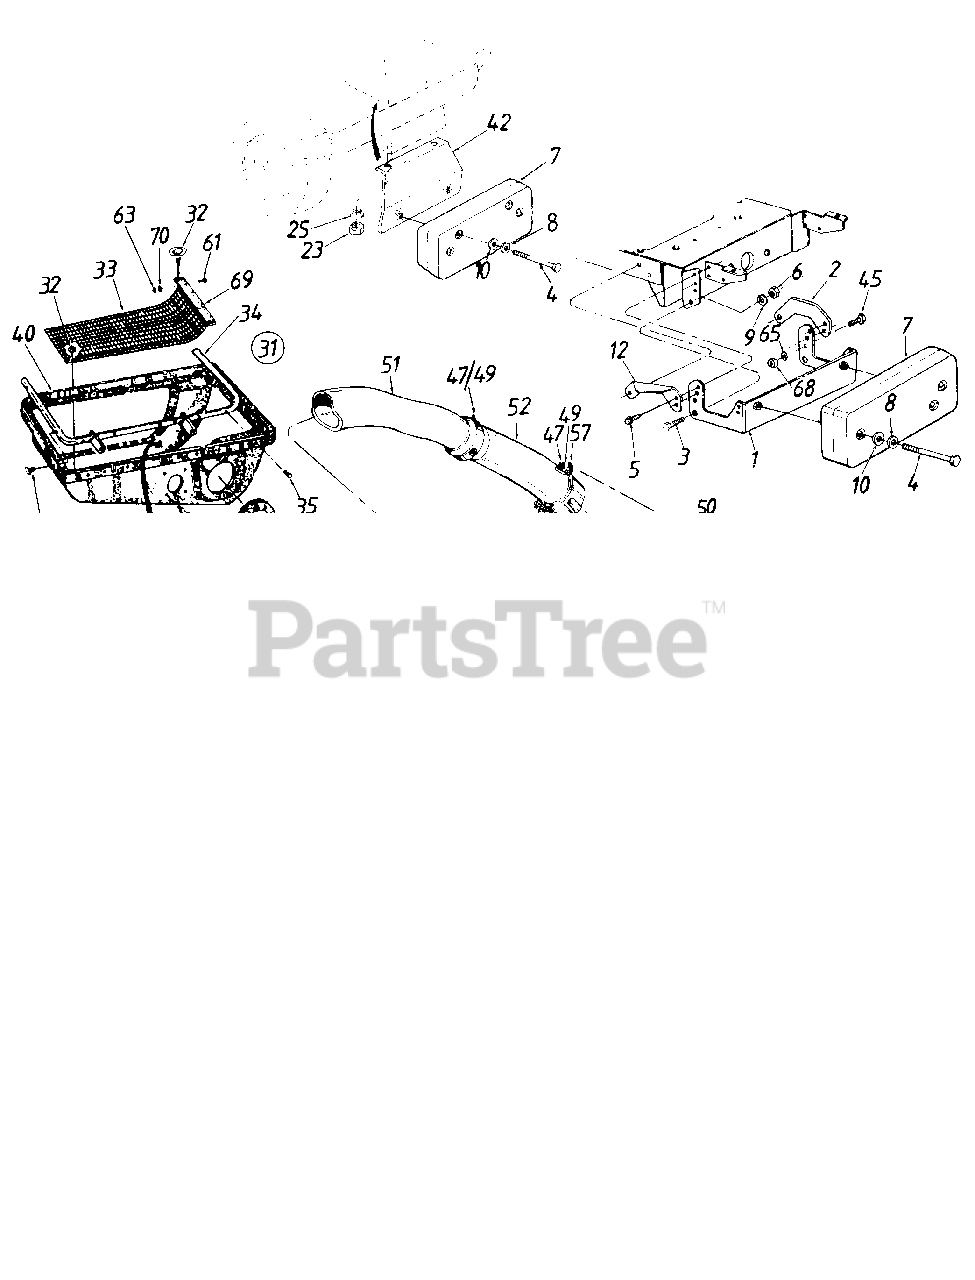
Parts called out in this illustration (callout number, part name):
1	Weight Brkt. Ass'y.
2	Weight Brkt. Tie Strap L.H.
3	Hex Bolt 7/16-20 x 1.0" Lg.
4	Hex Bolt 3/8-16 x 4.5" Lg.
5	Hex AB Tap Scr. 5/16-18 x 1.0"
6	Hex Jam Nut 7/16-20 Thd.
7	Front Counter Weight 38 lbs.
8	Bell.-Wash. 400" I.D. x .88" O.D.
9	L.-Wash. 7/16" I.D.
10	Fl.-Wash. .390" I.D. x 1.12" O.D.
12	Weight Brkt. Tie Strap R.H.
15	Catcher Support Tube Mtg. Brkt.
16	Catcher Support Tube Ass'y.
18	Catcher Latch and Support Brkt
19	Grass Catcher Support Brkt. R.H.
20	Grass Catcher Support Brkt. L.H.
21	Hex Bolt 5/16-18 x .75" Lg.
22	Hex Bolt 1/4-20 x .62" Lg. Grade 5
23	Hex Nut 5/16-18 Thd.
24	Hex Nut 3/8-16 Thd.
25	L.-Wash. 5/16" I.D.
26	L.-Wash. 3/8" I.D.
27	Shld. Bolt 3/8-16 x 500" Dia.
28	Bell.-Wash. .505" .D. x 1.00" O.D.
31	Grass Catcher Cover Ass'y.
32	Twist Fastener
33	Screen
35	Hex Tap Scr. 1/4-20 x .5" Lg. N
36	Seal
37	Truss Mach. B-Tap Scr. #10 x .5" Lg.
38	Plastic Plate
39	Speed Nut
40	Grass Catcher Cover
41	Hex Bolt 5/16-18 x 1.0" Lg.
42	Counterweight Support Brkt.
43	Grass Catcher Support Brkt. R.H.
44	Grass Catcher Support Brkt- L.H.
45	Hex Bolt 1/4-20 x .88" Lg.
47	Hex Bolt 1/4-20 x .50" Lg.
49	Hex Ins. L.-Nut 1/4-20 Thd.
50	Retainer Strap Ass'y.
51	Catcher Elbow
52	Catcher Tube
53	Discharge Chute
54	L.-Wash. .270" I.D. x .57" O.D.
57	Retainer Hook Brkt.
61	Truss Mach. Scr. #10-24 x .50" Lg.
62	Hex Bolt 1/4-28 x .75" Lg.
63	Hex Sems Nut #10-24 Thd.
64	Hex Nut 1/4-28 Thd.
65	L.-Wash. 1/4" I.D.
67	Grass Catcher Bag.
68	Hex Nut 1/4-20 Thd.
69	Screen Mtg. Brkt.
70	Flat Wash. 1/4" I.D.
